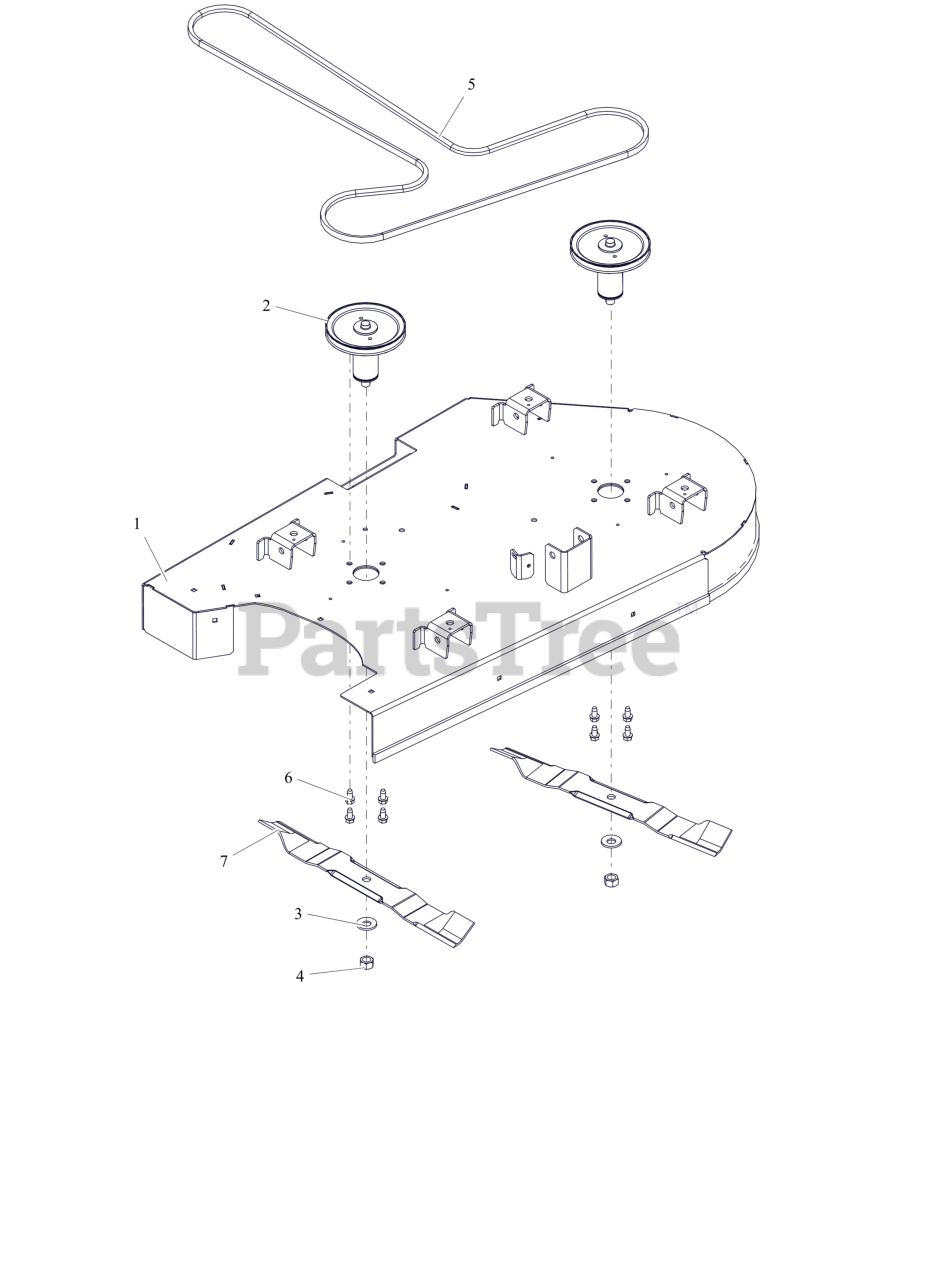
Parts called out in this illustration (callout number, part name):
1	WLDMT, DECK - 42" (ORANGE)
2	KIT, DECK SPINDLE ASM-60
3	WSHR-BLVL .669X1.535X.138
4	NUT-STD .625-18 ZCC
5	V-BELT, HA-WRAPPED
6	SCR,TAP .375-16X.75 HWH TR ZCC
7	BLADE, 21" 35 DEG
